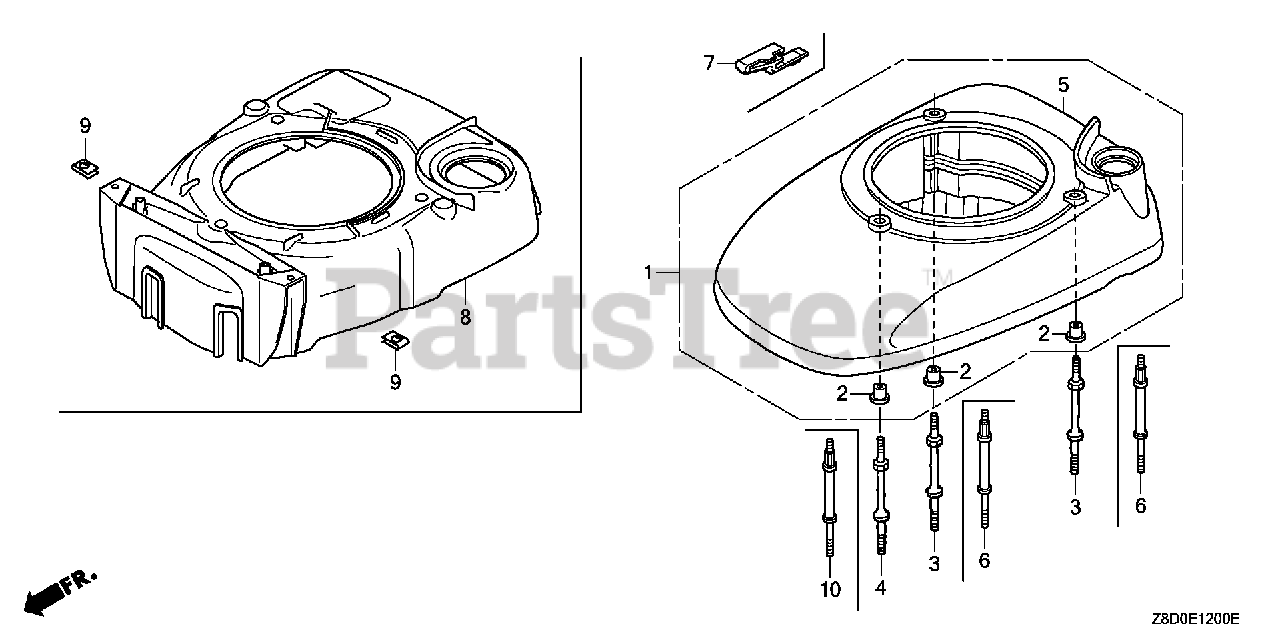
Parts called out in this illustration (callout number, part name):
5	COVER, FAN *R280* (POWER RED)
5	COVER, FAN *NH1* (BLACK)
5	COVER, FAN *T114* (LIBERTY RED)
5	COVER, FAN *T113* (CRAFTSMAN GRAY)
6	BOLT, STUD (FAN COVER)
7	CLIP, TANK MOUNTING *R280* (POWER RED)
7	CLIP, TANK MOUNTING *NH1* (BLACK)
7	CLIP, TANK MOUNTING *T114* (LIBERTY RED) (NOT AVAILABLE)
7	CLIP, TANK MOUNTING *T113* (CRAFTSMAN GRAY) (NOT AVAILABLE)
10	BOLT, STUD (FAN COVER)
